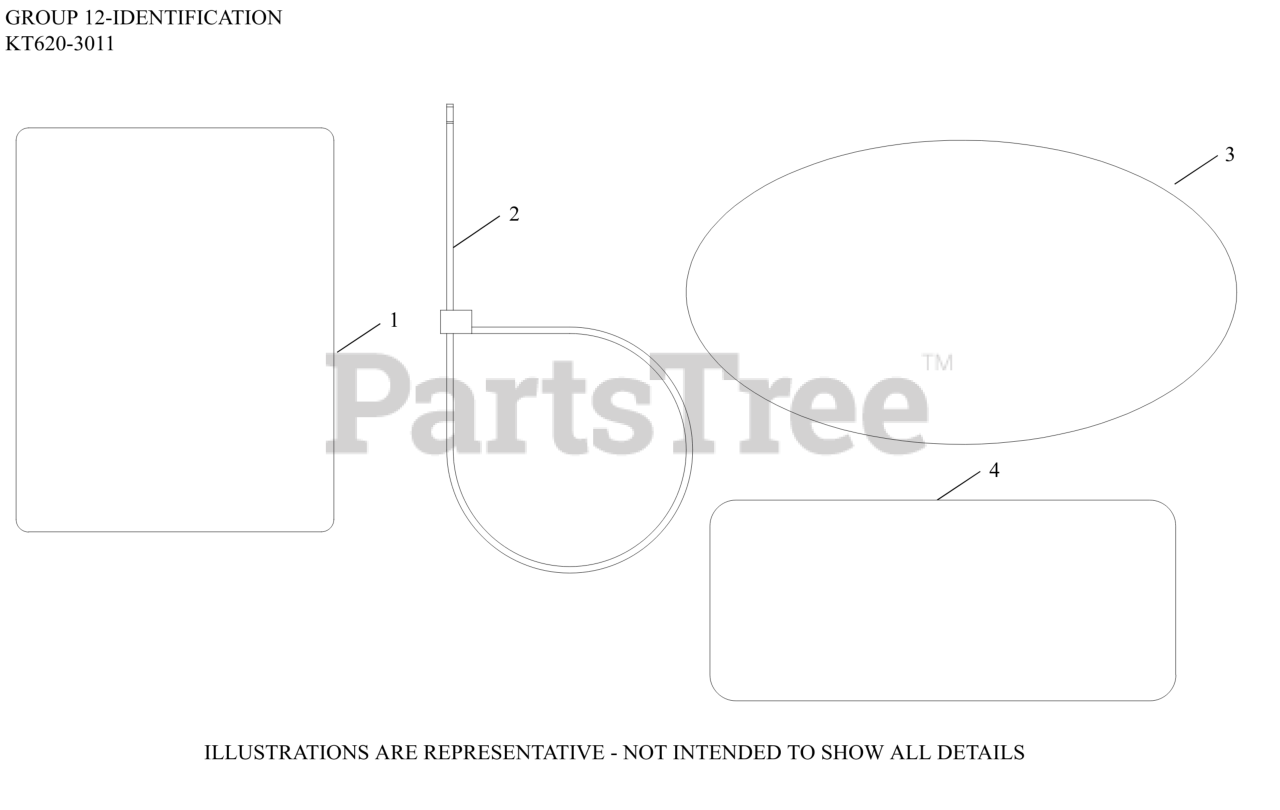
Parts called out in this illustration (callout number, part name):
1	LABEL, CLEAR LAMINATION
3	LABEL, 6000 SERIES (21HP)
4	LABEL, CANADIAN COMPLIANCE
